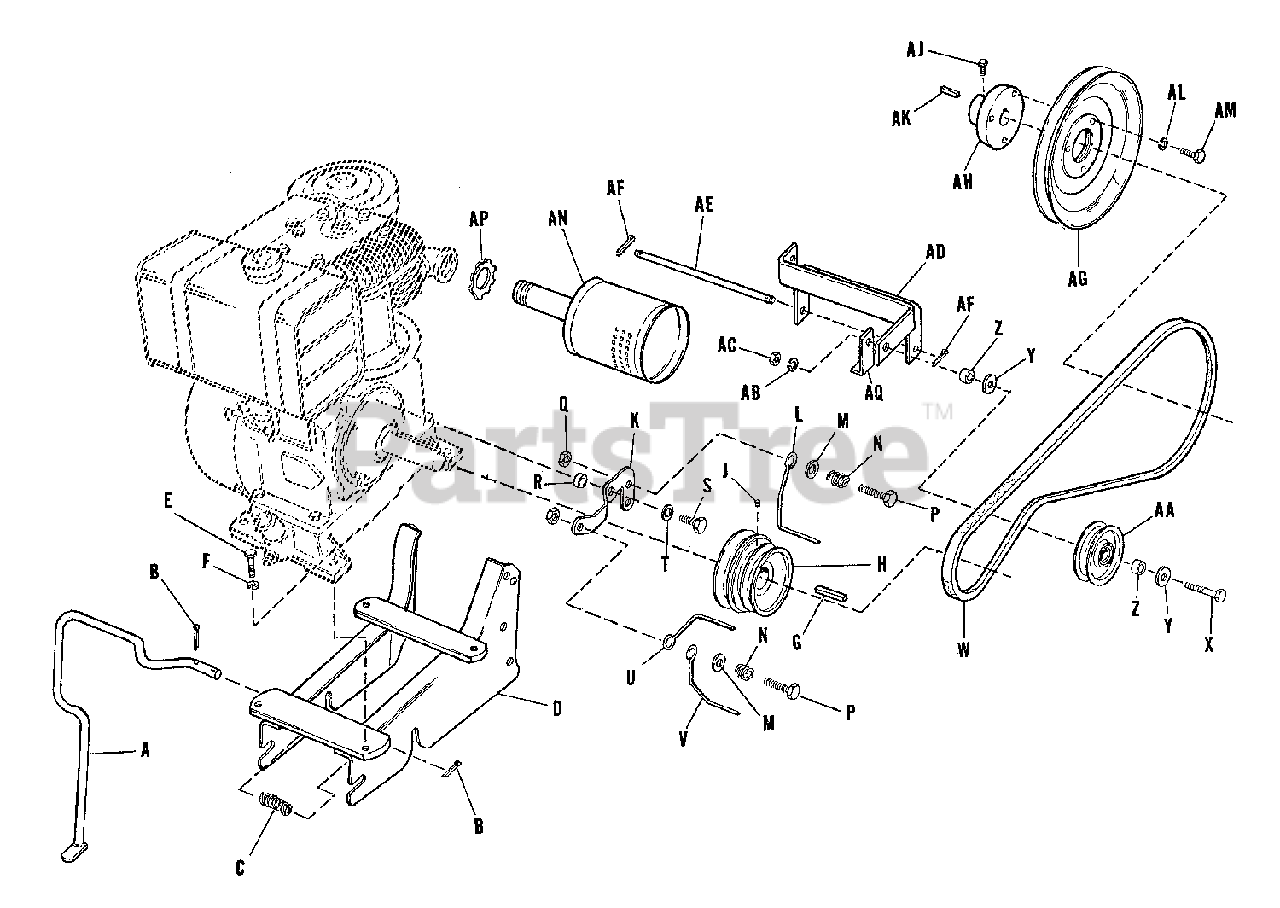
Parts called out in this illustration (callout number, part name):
A	STAND ASSEMBLY
B	PIN, Cotter, 1/8" Diameter x 1" LG
C	SPRING, Stand
D	BASE ASSEMBLY, Engine
E	CAPSCREW, Hex Head, 3/8-16 NC x 1-1/4" LG
F	WASHER, Lock, 3/8"
H	PULLEY, Engine
J	SCREW, Set, Cup Point, 5/16-18 NC x 5/16" LG
K	HOLDER, Belt Stop
L	STOP, Belt
M	WASHER, Plain, 5/16"
P	CAPSCREW, Hex Head, 5/16"-18 NC x 1-1/4" LG
Q	NUT, Hex, Jam, 5/16"-18 NC
S	CAPSCREW, Hex Head, 5/16"-18 NC x 1" LG
T	WASHER, Lock, 5/16"
U	STOP, Belt
V	STOP, Belt
W	BELT, "V"
X	CAPSCREW, Hex Head, 3/8"-16 NC x 1-3/4" LG
Y	WASHER, Plain, 5/16"
AA	PULLEY, Idler
AB	WASHER, Lock, 3/8"
AC	NUT, Hex, Full, 3/8"-16 NC
AD	PIVOT ASSEMBLY, Idler
AE	ROD, Pivot
AF	PIN, Cotter, 3/32 Diameter x 7/8" LG
AG	PULLEY, Transmission
AH	HUB, Pulley
AJ	SCREW, Set, Square Head, 5/16"-18 NC x 3/8" LG
AK	KEY, Transmission Pulley
AL	WASHER, Lock, 5/16"
AM	CAPSCREW, Hex Head, 5/16"-18 NC x 7/8" LG
AN	MUFFLER, Exhaust
AP	NUT, Lock, Full Hex, 3/8-24
